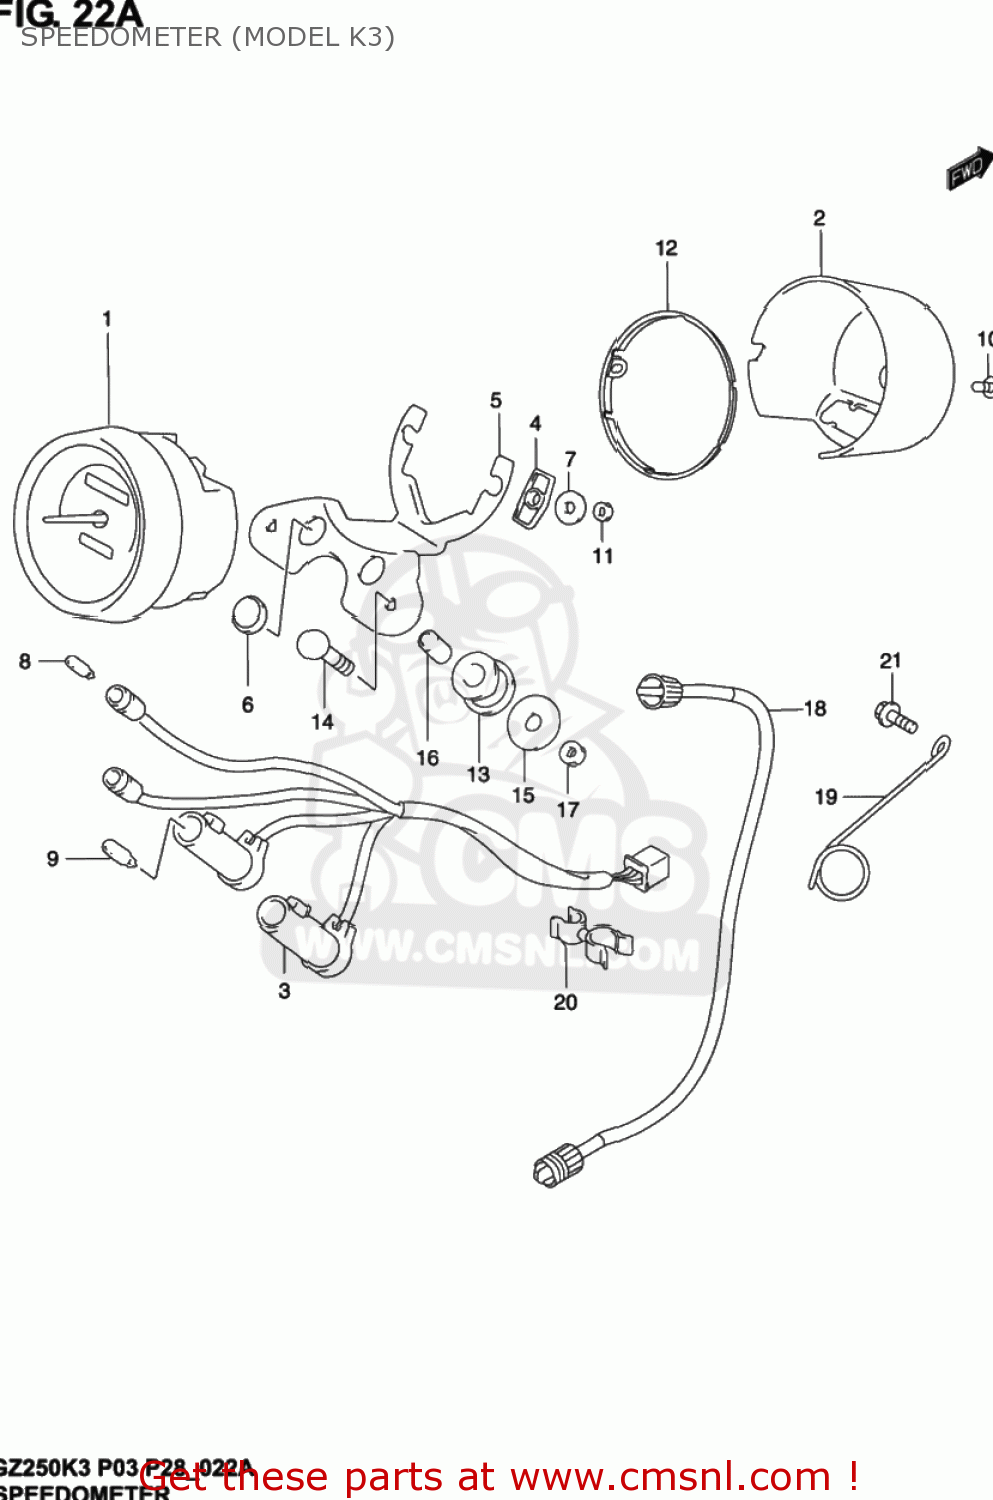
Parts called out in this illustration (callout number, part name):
1	SPEEDOMETER
2	COVER, UNDER
3	SOCKET, ASSY
4	CUSHION,DAMPER
5	BRACKET, METER
6	LENS, GREEN
7	WASHER
8	BULB(12V3.4W,T10)
9	BULB(12V1.7W,T6.5)
10	SCREW,METER
11	NUT
12	PACKING (NAS)
13	CUSHION,METER BRACKET
14	BOLT(6X30)
15	WASHER(6.5X28X1.6)
16	SPACER(6.5X10X16.5)
17	NUT 6MM
18	CABLE ASSY,SPEEDOMETER
19	GUIDE,SPEEDOMETER CABLE
20	CLAMP
21	BOLT
